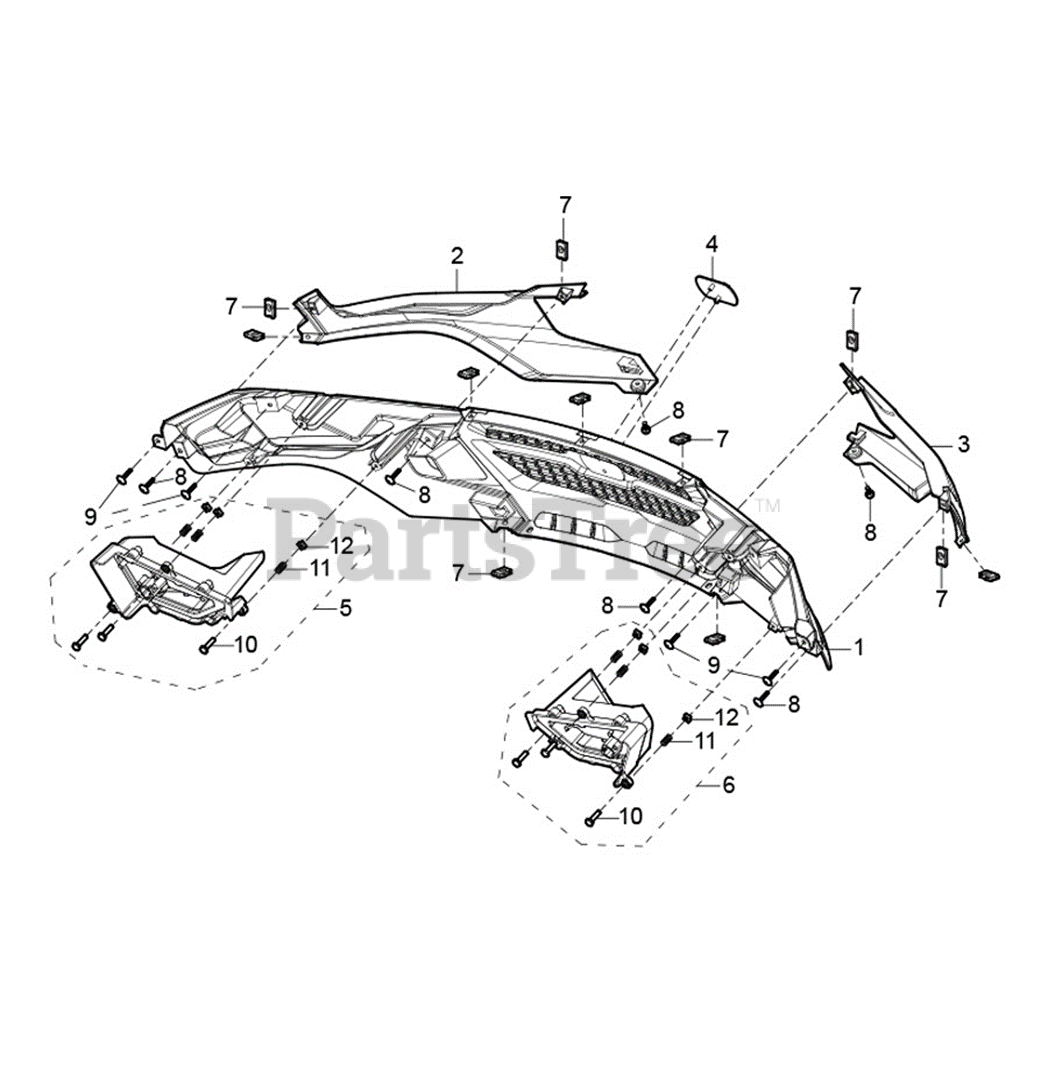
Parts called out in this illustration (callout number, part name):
1	HEAD LIGHT DASH
2	COVER HEAD LAMP (LEFT) RED
2	COVER HEAD LAMP LEFT (YELLOW)
2	COVER HEAD LAMP LEFT BLUE
2	COVER HEAD LAMP LEFT BLACK
2	COVER HEAD LAMP LEFT CAMO
3	COVER HEAD LAMP (RIGHT) RED
3	COVER HEAD LAMP RIGHT (YELLOW)
3	COVER HEAD LAMP RIGHT BLUE
3	COVER HEAD LAMP RIGHT BLACK
3	COVER HEAD LAMP RIGHT CAMO
4	HOOD BADGE
5	HEAD LIGHT ASSEMBLY - LEFT
6	HEAD LIGHT ASSEMBLY - RIGHT
7	CLAMP NUT M6X6
8	SOCKET HEX FLAT HEAD BOLT M6X16
9	HEX HEAD FLANGE BOLT M6X12
10	HEX HEAD BOLT (6x30)
11	COMPRESSION SPRING
12	SQUARE NUT M6
